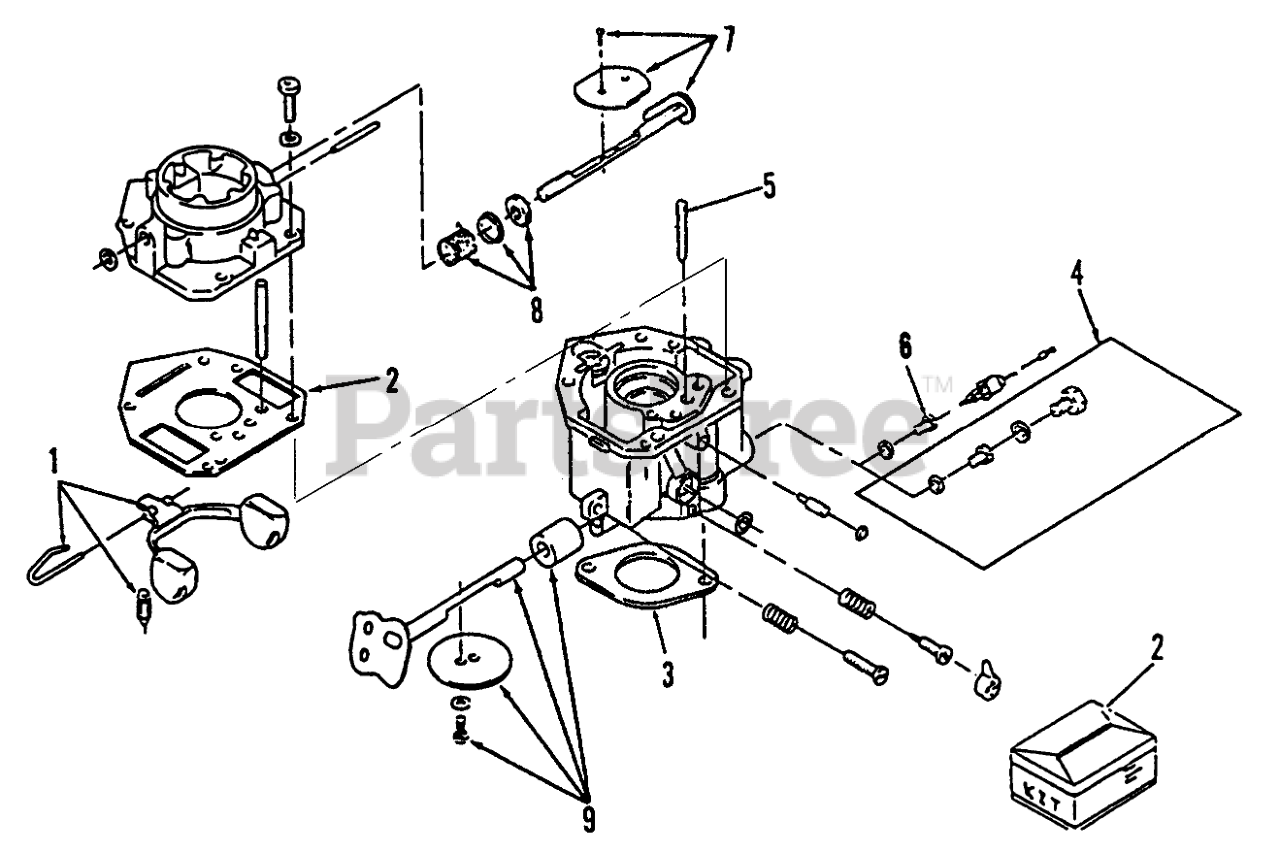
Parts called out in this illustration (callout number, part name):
1	Kit-Float (Incl. Float, Pin, & Valve)
2	Kit-Repair (Incl. Screw & Plug Package, Gasket Package, Float Valve, Idle Adjustment Needle & Spring, Mounting Gaskets, & Idle Limit Cap)
3	GASKET-CARBURETOR
4	FIXED-JET PKG
5	Idle Jet
6	POWER JET
7	Kit-Choke Shaft (Incl. Choke Valve, Valve Screw-Set, & Air Filter)
8	Kit-Choke Lever (Incl. Choke Lever Ring, Choke Spring, & Choke Collar)
9	Kit-Throttle Shaft (Incl. Valve Screw-Set, Air Filter, & Throttle Valve)
